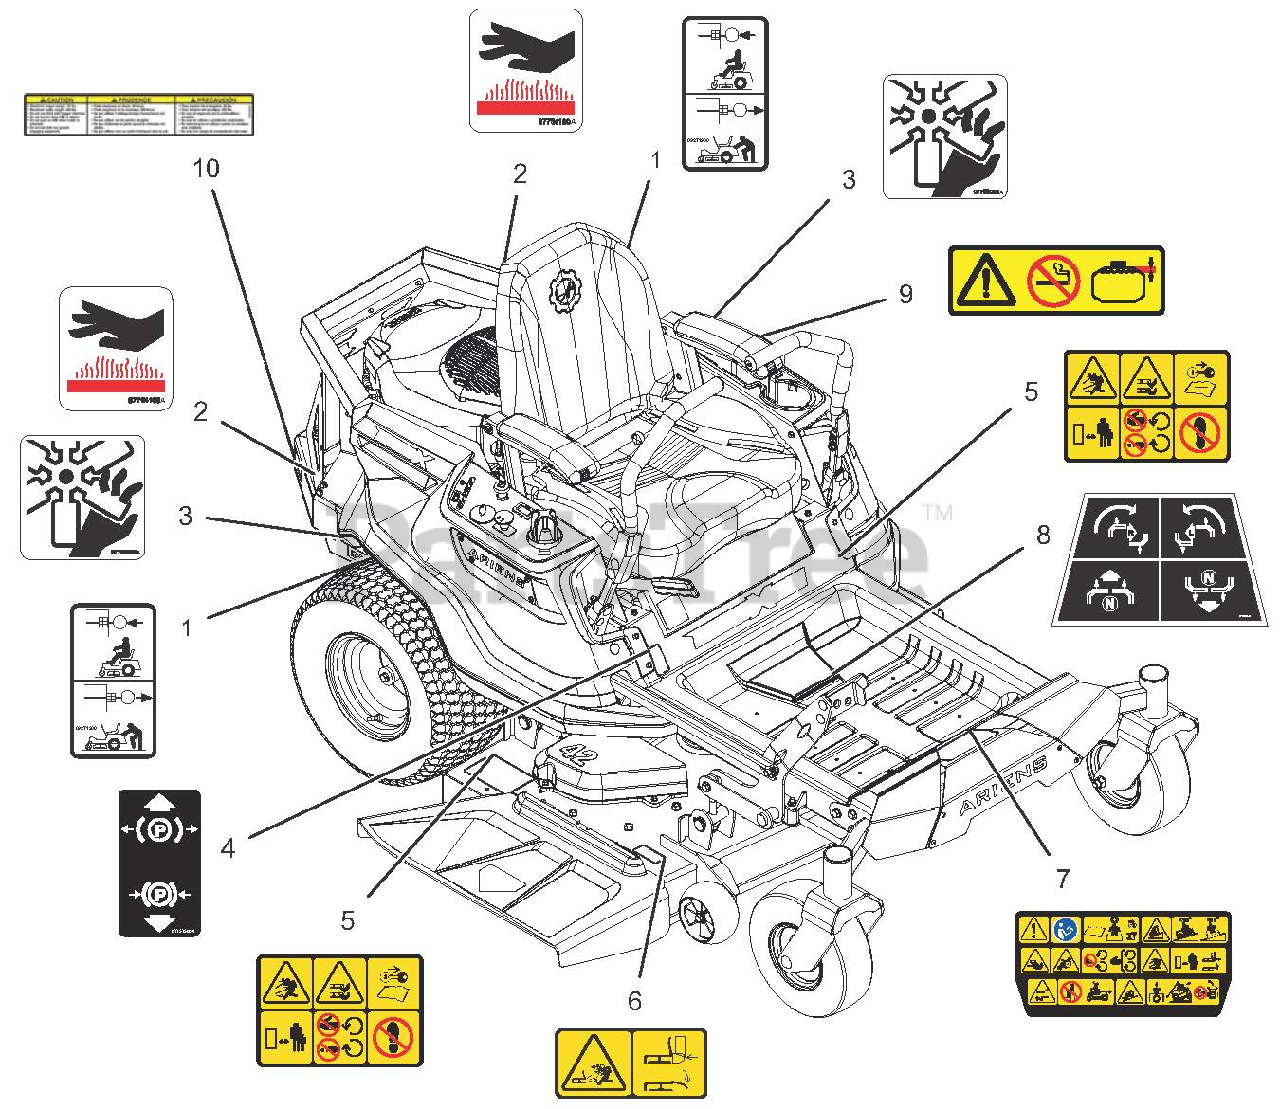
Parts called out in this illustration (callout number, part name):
1	DECAL, TRANSMISSION DISCONNECT
2	DECAL, HOT SURFACE
3	DECAL, DANGER FAN
4	DECAL, PARKING BRAKE LEVER
5	DECAL, SAFETY - MOWER DECK
6	DECAL, SAFETY - DECK GUARDING
7	DECAL, MAIN SAFETY
8	DECAL, STEERING
9	DECAL, FUEL WARNING
10	DECAL, TRAILER HITCH
